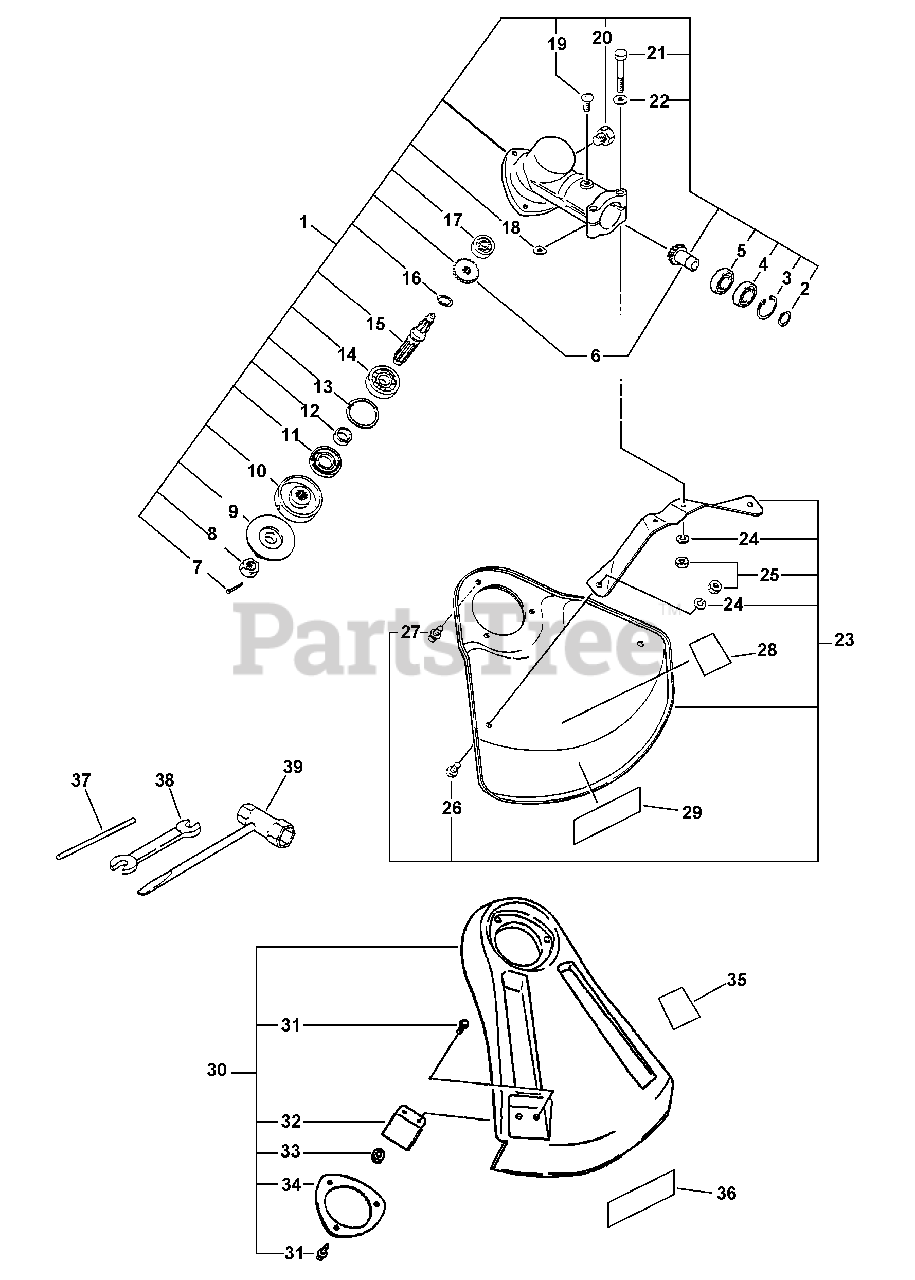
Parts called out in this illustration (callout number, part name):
1	GEAR CASE ASSY
2	RING, SNAP Ø10
3	RING, SNAP Ø22
4	BEARING, BALL 6900Z
5	BEARING, BALL 6900
6	GEAR SET
7	PIN, COTTER 2×22
9	PLATE, ADAPTOR - LOWER
10	PLATE, ADAPTER - UPPER
11	SEAL, OIL 22
12	SPACER 11.8×15×9
13	RING, SNAP Ø32
14	BEARING, BALL 6201
15	SHAFT, GEAR
16	RING, SNAP Ø12
17	BEARING, BALL 609
19	SCREW 5×10
20	BOLT 8×6
21	BOLT 5×35 SP
22	WASHER, FLAT 5.5×10×0.8
23	SHIELD ASSY
24	WASHER, SPRING 5
25	NUT M5
26	SCREW 5×8
27	SCREW 5×10
28	LABEL, ECHO
28	LABEL, CAUTION
30	DEBRIS SHIELD KIT
31	SCREW 5×16
32	CUTTER, LINE
33	NUT M5
34	BRACKET, SHIELD
35	LABEL, CAUTION
36	LABEL, ECHO
37	TOOL, LOCKING 5×120 MM
38	SPANNER 8×10
39	T-WRENCH
